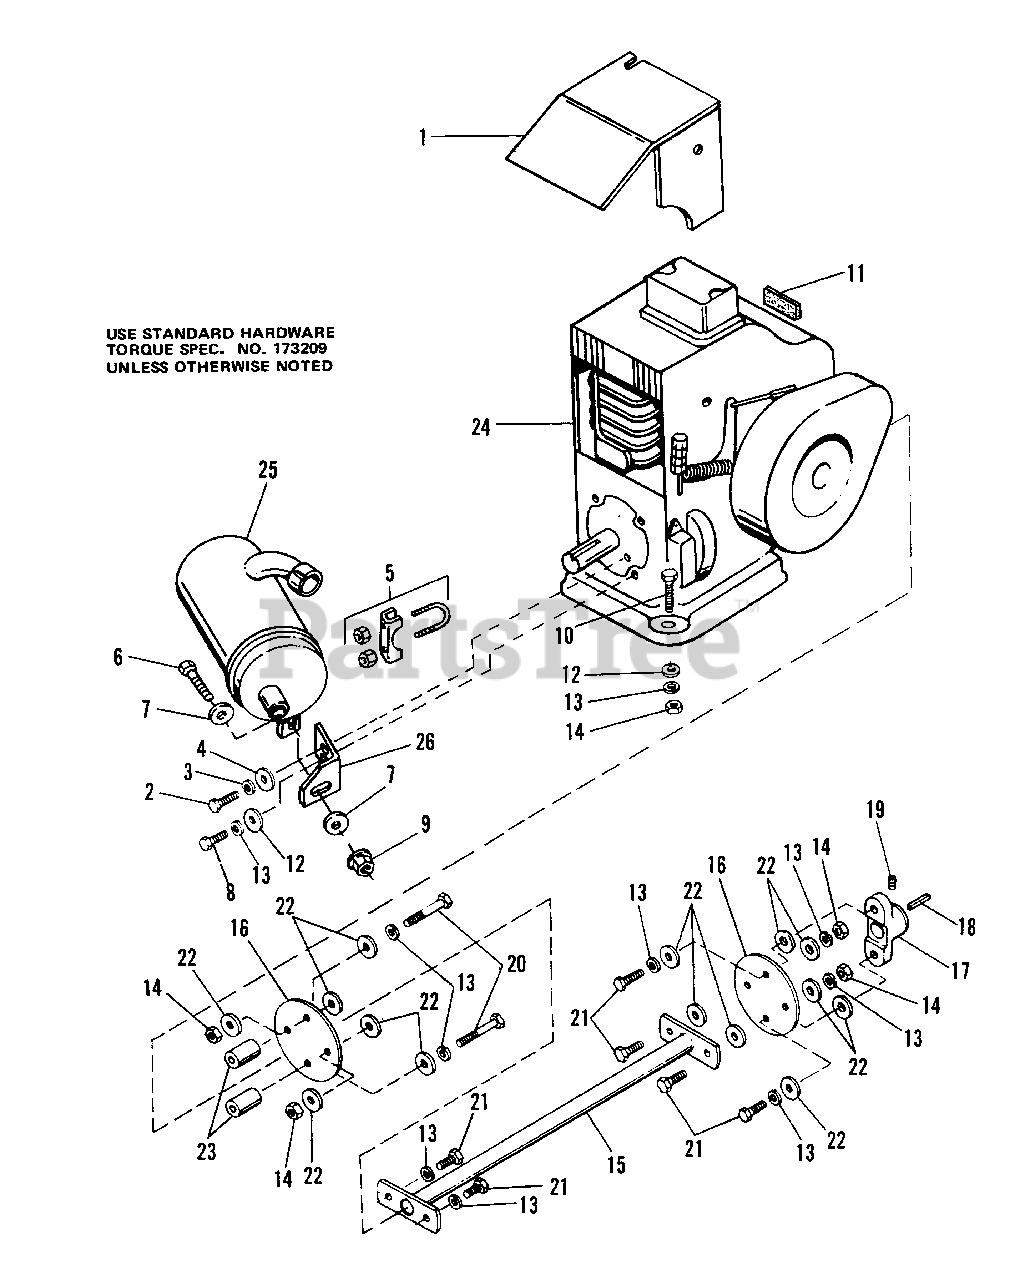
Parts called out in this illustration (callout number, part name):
1	DEFLECTOR ASSY
2	CAPSCREW, Hex Hd., 7/16-14 x 3/4
3	LOCKWASHER, 7/16
4	WASHER, Plain, 7/16
5	CLAMP, Exhaust
6	CAPSCREW, Hex Hd., 5/16-18 x 1
7	WASHER, Plain 5/16
8	CAPSCREW, Hex Hd., 3/8-16 x 3/4
9	LOCKNUT, Flange, Whizlock, 5/16-18
10	CAPSCREW, Hex Hd., 3/8-16 x 1-1/2
11	PAD, Felt
12	WASHER, Plain, 3/8
13	LOCKWASHER, 3/8
14	NUT, Hex, 3/8-16
15	SHAFT ASSY, Drive
17	FLANGE, Drive
18	KEY, Driveshaft
19	SETSCREW, 3/8-24 x 3/8
20	CAPSCREW, Hex Hd., 3/8-16 x 2-1/4
21	CAPSCREW, Hex Hd., 3/8-16 x 1-1/4
22	WASHER, Special
24	ENGINE, 18 h.p., Kohler
25	MUFFLER, Exhaust
26	BRACKET, Muffler
